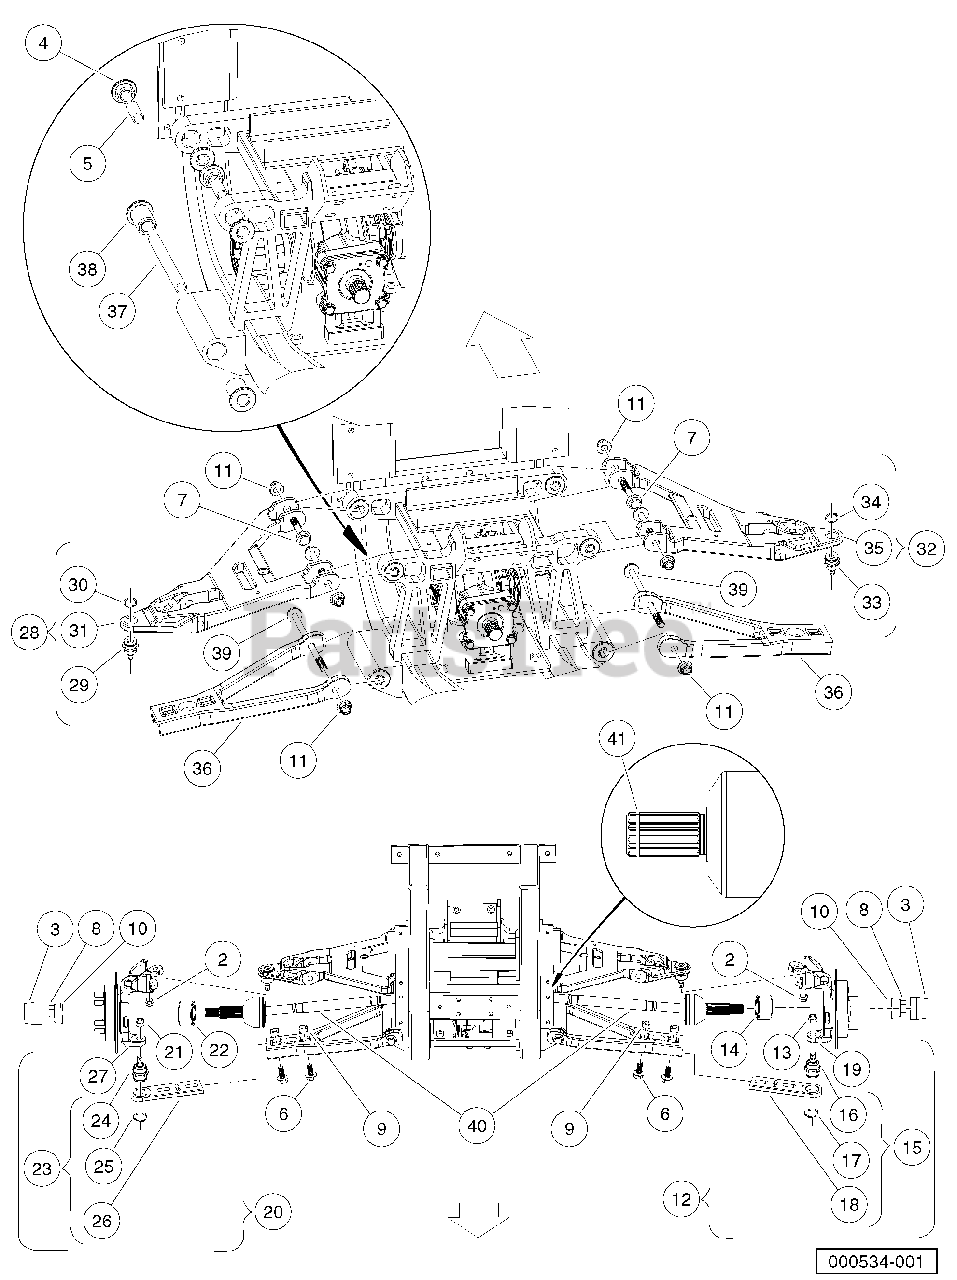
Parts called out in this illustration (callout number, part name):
1	Suspension, AWD, Wide
2	Locknut, M12-1.25 Nylon
3	Center Cap, Rubber
4	Bushing, A-Arm
5	Sleeve, Upper
6	Bolt, Flange Head, M12x 1.75x 30 with Loctite
7	Bolt, Flange Head, M12 X 1.75 X 70
8	Nut Flg, M22 X 1.5 Mech Def
9	Nut, Square, M12x 1.75
10	Washer Hard, M22
11	Nut Flg, M12x1.75, Nylon Gr 10
12	Upright, Left-Hand
13	Locknut, M12-1.25 Nylon
15	Asm, Adjuster, Slide
16	Joint, Ball
17	Ring, Retaining, Ext, 1-1/4"
18	Slide, Adjuster
19	Upright, Finished, Lh
20	Upright, Right-Hand
21	Locknut, M12-1.25 Nylon
23	Asm, Adjuster, Slide
24	Joint, Ball
25	Ring, Retaining, Ext, 1-1/4"
26	Slide, Adjuster
27	Upright, Finished, Rh
28	Asm, A-Arm, Upper, Left
29	Joint, Ball
30	Ring, Retaining, Ext, 1-1/4"
31	Arm, Upper, Wide, Machined, Lh
32	Asm, A-arm, Upper, Right
33	Joint, Ball
34	Ring, Retaining, Ext, 1-1/4"
35	Arm, Upper, Wide, Machined,rh
36	A-Arm, Lower
37	Sleeve, Lower Arm
38	Bushing, Lower Arm
39	Bolt Flg, M12 X 1.75 X 200 10.
40	Half Shaft, Wide, Awd
41	Ring, Hog, Half Shaft
